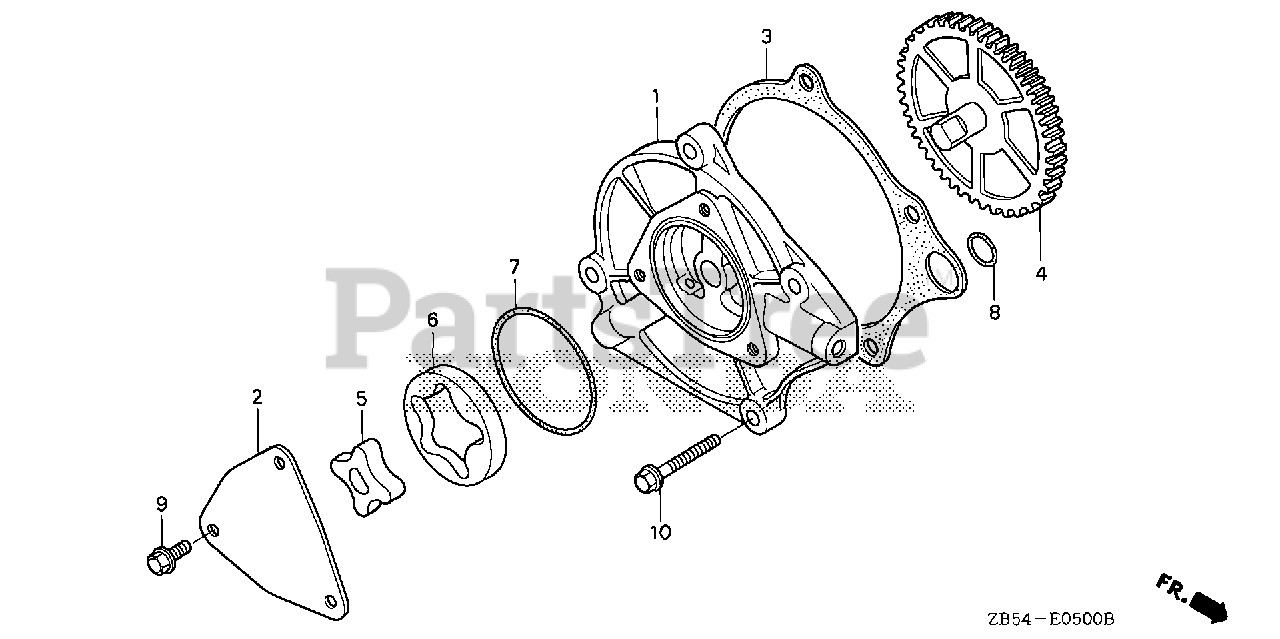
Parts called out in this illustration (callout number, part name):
1	BODY, OIL PUMP
2	COVER, OIL PUMP
3	GASKET, OIL PUMP
4	GEAR ASSY., OIL PUMP
5	ROTOR (INNER)
6	ROTOR (OUTER)
7	O-RING (45X2.5) (ARAI)
7	O-RING, PUMP COVER
8	O-RING (10.8X2.4) (ARAI)
9	BOLT, FLANGE (6X12) Use from Engine SN 2086984.
10	BOLT, FLANGE (6X25)
